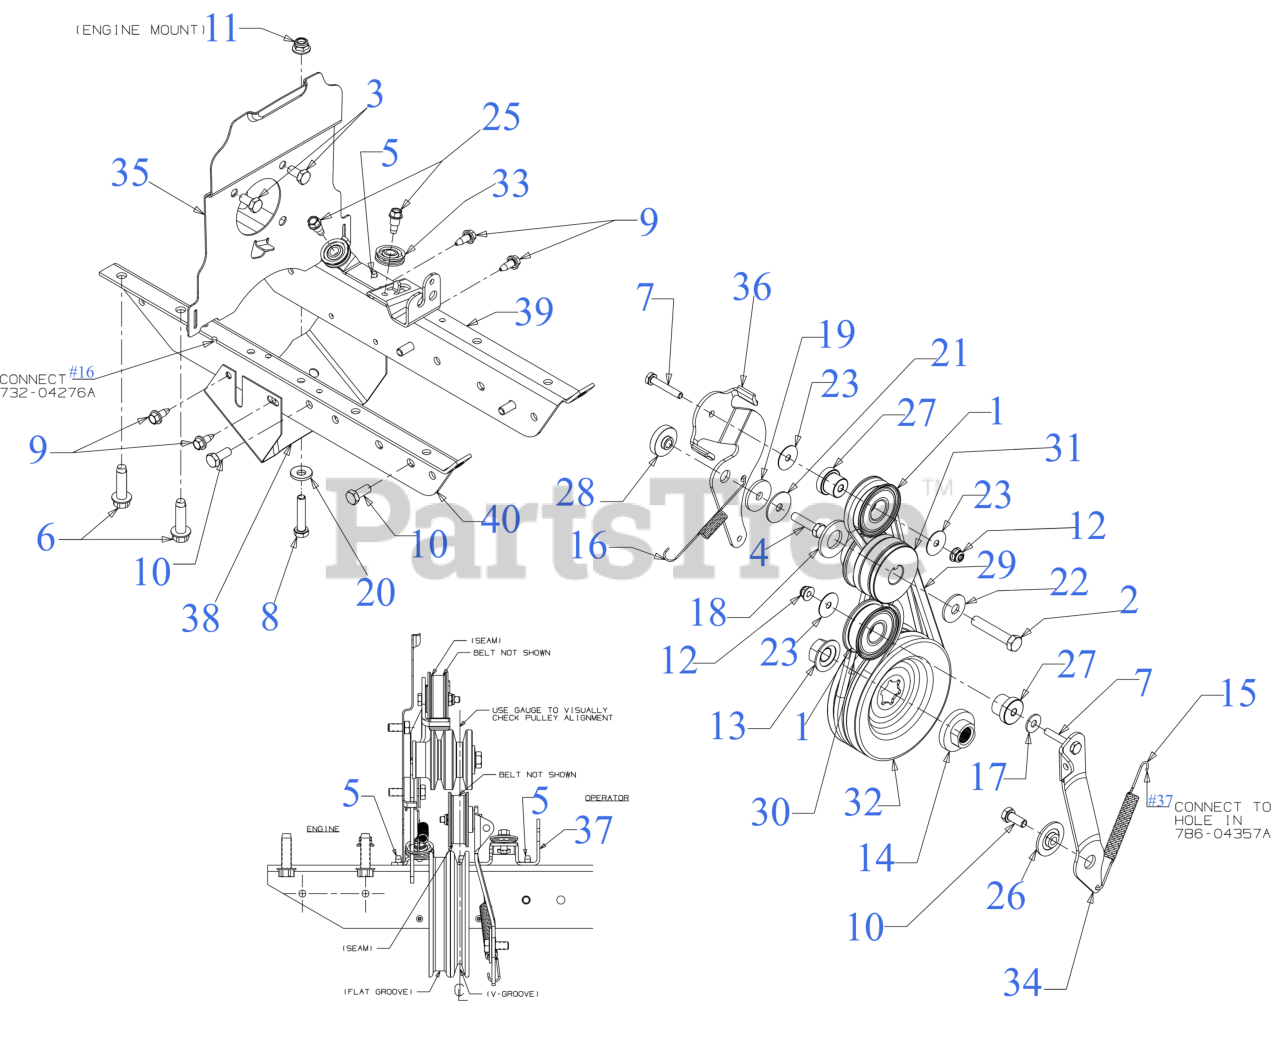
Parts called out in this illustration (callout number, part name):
1	IDLER PULLEY ASSEMBLY
2	HEX SCREW 3/8-24 X2.00
3	HEX SCREW 5/16-24 x .62
4	SCREW 5/16-24 x 1.25 GR5
5	SCREW 1/4-20 X.500
6	SCREW 3/8-16 x 1.375
6	SCREW 3/8-16 x 1.250
7	SCREW 1/4-20 x 1.50 GR.5
8	SCREW 5/16-18 x 1.5 LG
9	SCREW 1/4-14 x .625
10	SCREW 5/16-18 x .750
11	FLANGE LOCK NUT 5/16-18
12	FLANGE LOCK NUT
13	FLANGE NUT W/HUB
14	PULLEY HUB
15	RETURN SPRING
16	EXTENSION SPRING
17	FLAT WASHER .28 ID x .74 OD x .063
18	FLAT WASHER
19	WASHER-5/16 x 1.25X 1.27
20	BELLVILLE WASHER .827 x .331 x .098
21	FLAT WASHER 0.315x1.255x0.060 HD
22	BELL WASHER
23	FLAT WASHER
25	SHOULDER SCREW
26	PIVOT IDLER SPACER
27	SHOULDER SPACER
28	PIVOT IDLER SPACER
29	V-BELT 4L x 25.375
30	V-BELT 3L x 29.125
31	ENGINE PULLEY
32	TRANSMISSION PULLEY
33	CABLE GUIDE ROLLER
34	FORWARD IDLER BRACKET
36	REVERSE IDLER BRACKET
39	FRAME-MOUNT (RH)
